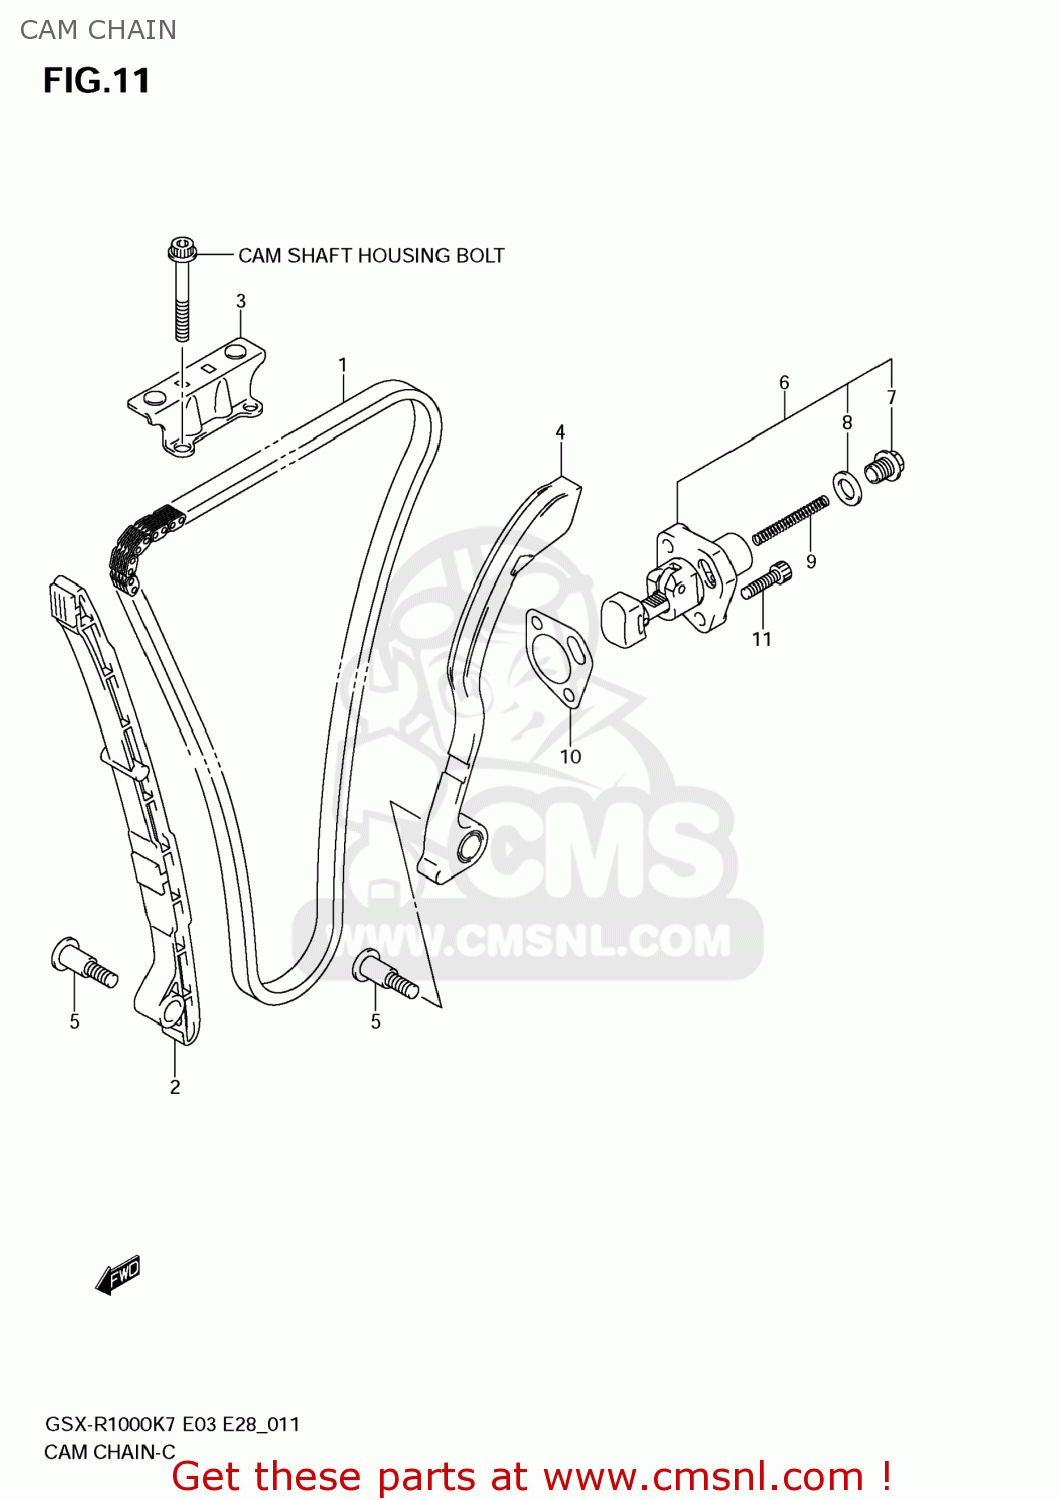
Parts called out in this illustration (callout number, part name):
1	CHAIN,CAMSHAFT DRIVE
2	GUIDE,CAM CHAIN NO.1
3	GUIDE CAM CHAIN NO,2
4	TENSIONER,CAM CHAIN
5	BOLT,CAM CHAIN TENSIONER
6	ADJUSTER ASSY,TENSIONER
7	PLUG,FR TENSIONER ADJ
8	GASKET,TENSIONER ADJUSTER (NAS)
9	SPRING
10	GASKET,TENSIONER ADJUSTER (NAS)
11	BOLT
